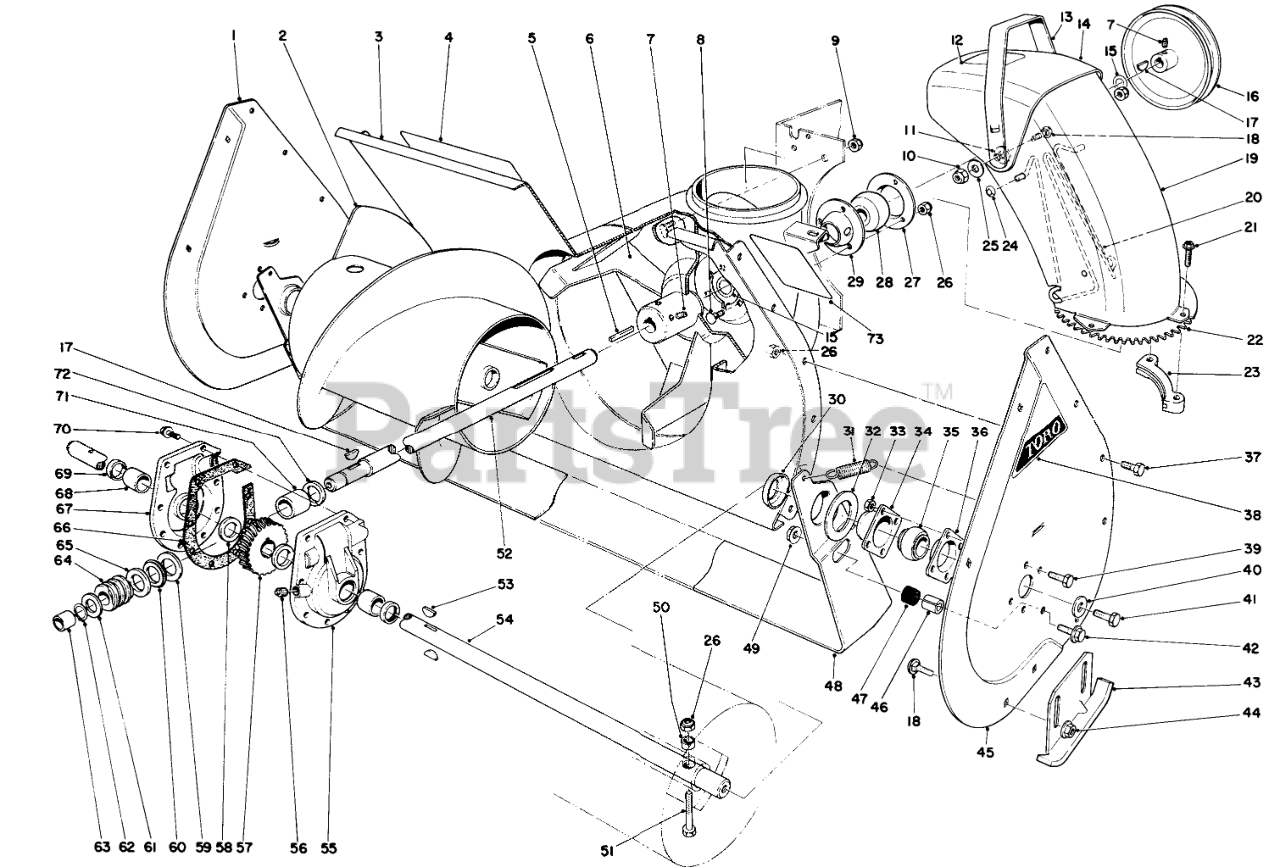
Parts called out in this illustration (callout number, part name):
1	RH AUGER SIDE PLT R
2	Auger Right
3	AUGER HSG WA RO
4	AUGER WARNING DECAL
6	IMPELLER WA RO
7	SCREW-SET, SQH
8	BOLT-CARR
9	NUT-LOCK, NI
10	NUT-LOCK, CONE
11	WASHER-RUBBER
12	DECAL-DANGER DISCH.
13	DEFLECTOR HANDLE B
14	Deflector Chute (Incl. Ref. #12)
15	WASHER
16	IMPELLER PULLEY
17	KEY-WOODRUFF
18	SCREW-CARR
19	CHUTE B
20	CHUTE WIRE
21	SPECIAL SCREW
22	Gear-Chute Swivel
23	CHUTE RETAINER
24	NUT-PUSH
25	WASHER-BELLEVILLE
26	NUT-LOCK, NI
27	FLANGE-CUP, BEARING
28	Ball Bearing
29	FLANGE-CUP, BEARING
30	Positioner-Scraper
31	SPRING-TENSION
32	SCRAPER BLADE SPACER
33	NUT-LOCK, CONE
34	BEARING-FLANGE, FRONT
35	BEARING
36	BEARING-FLANGE, REAR
37	SCREW-HH
38	AUGER SIDE PLT DECAL
39	SCREW-HH
40	WASHER
41	SCREW-HH
42	SCREW-HHF
43	AUGER SKID WA R
44	NUT-HHF, WHIZ
45	LH AUGER SIDE PLT R
46	SCRAPER STOP SPACER
47	SCRAPER STOP CUSHION
48	24 SCRAPER BLD
49	NUT-HF
50	SPACER-HUB, AUGER
51	Auger Bolt
52	Shaft Impeller
53	KEY-WOODRUFF
54	24 AUGER SHAFT
55	Gear Case (Incl. Ref. #68 & 69)
56	PLUG-PIPE, SQH
57	GEAR-WORM, 27T
58	WASHER-THRUST
59	WASHER-THRUST
60	BEARING-THRUST
61	WASHER-THRUST
62	Ring-Snap
63	BUSHING
65	THRUST-WASHER
66	GASKET-CASE, GEAR
67	Gear Case (Incl. Ref. #68 & 69)
68	BUSHING
69	SEAL-OIL
70	SCREW-TAPTITE
71	BUSHING-SPECIAL
72	RING-QUAD
73	DECAL-WARNING, AUGER
